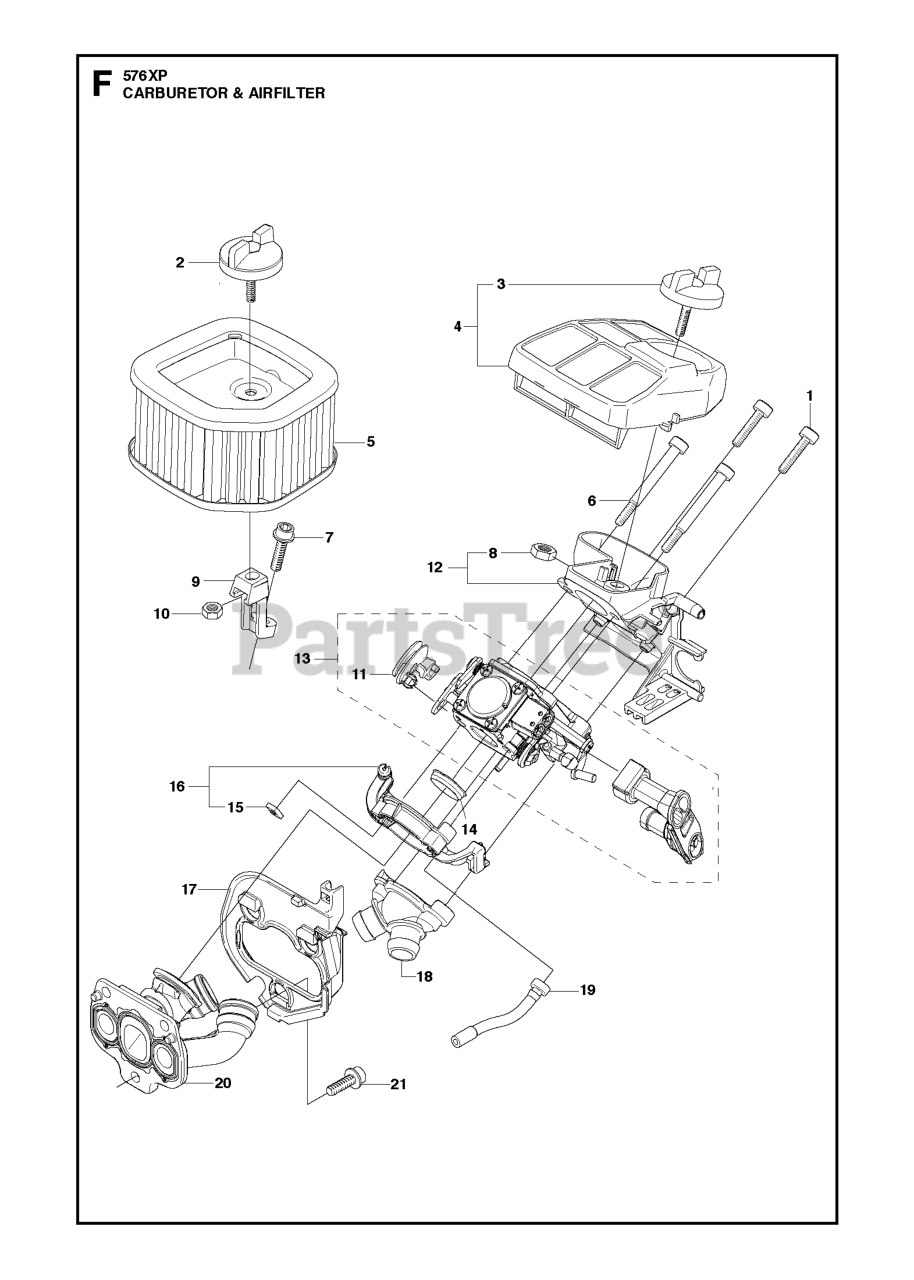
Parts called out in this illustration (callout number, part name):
4	AIR FILTER
5	AIR FILTER
5	AIR FILTER HD 44
5	AIR FILTER WINTER
6	SCREW 4X46
12	FILTER HOLDER
13	CARBURETOR
20	PIPE
